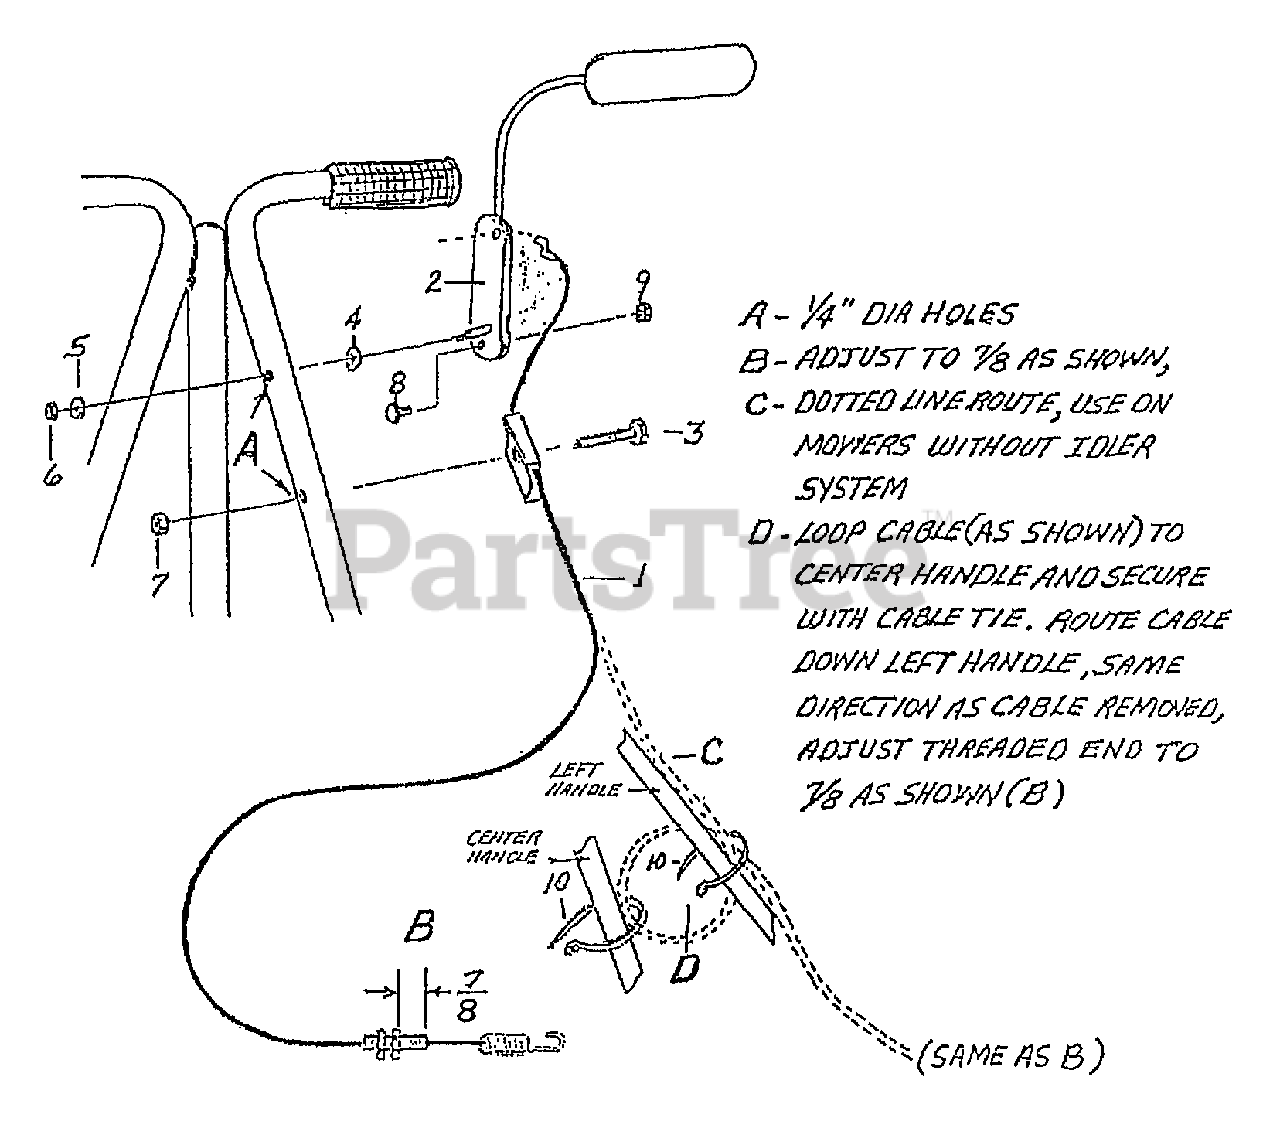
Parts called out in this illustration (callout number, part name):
1	BLADE BRAKE CONTROL CABLE
2	BLADE CONTROL LEVER
3	SCREW 1/4-20X1.5 G5ZP
4	WASHER-FLAT 1/4
5	WASHER, 3/16 FLAT
6	NUT 10-24 NYLON LOCK
7	NUT-LK 1/4-20
8	SCR-HH #10-24X.375
9	NUT-3/16 HEX LOCK
10	CABLE TIE
